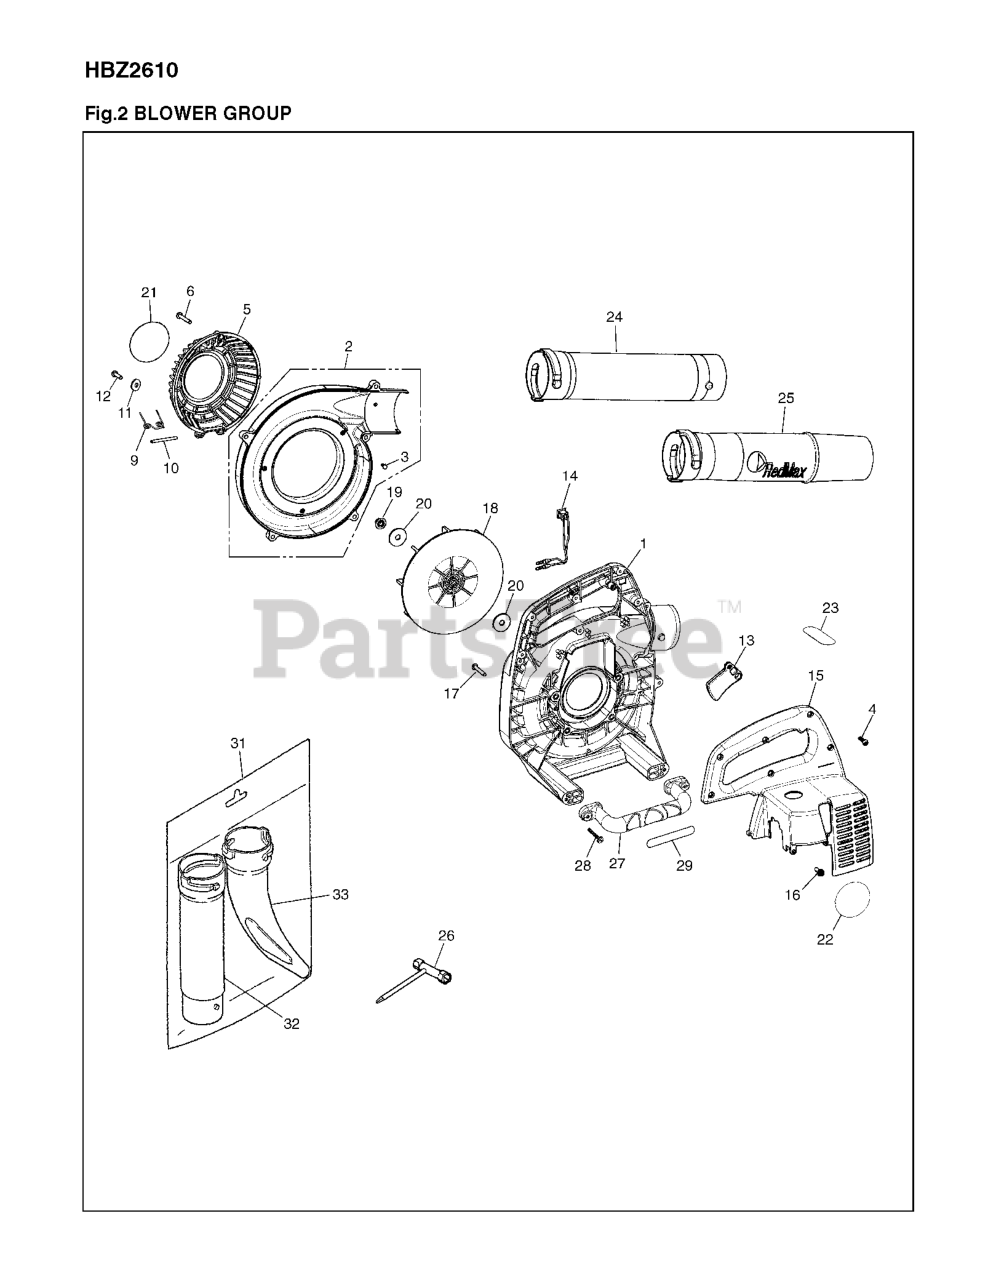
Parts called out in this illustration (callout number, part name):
1	VOLUTE CASE
2	VOLUTECOVER(HBZ2600)T402211300
3	SCREW
4	SCREW, TORX (RPLS T4970-52001)
5	GUARD.NET
15	ENGINE COVER
19	NUT
23	LABEL,CAUTION
24	PIPE STRAIGHT
25	PIPE.END
29	LABEL-A.HANDLE
31	FLAT NOZZLE KIT
32	PIPE STRAIGHT
33	FLAT NOZZLE
